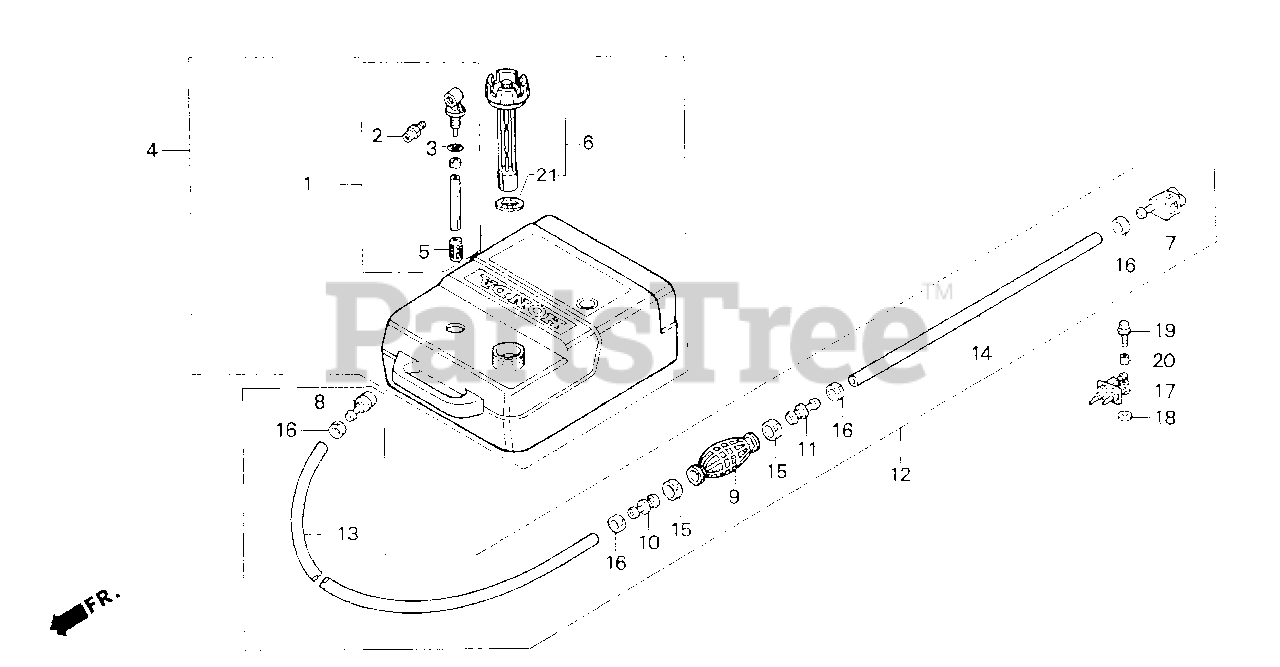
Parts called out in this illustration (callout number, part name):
1	JOINT ASSY., FUEL
2	FITTING, QUICK DISCONNECT
3	O-RING
4	TANK ASSY., FUEL
4	TANK, FUEL (25 LITER)
5	FILTER, FUEL
6	CAP, FUEL FILLER
7	CONNECTOR SET, FUEL
7	CONNECTOR ASSY. A, FUEL
8	CONNECTOR, FUEL
9	PRIMER BULB
10	VALVE, IN.
11	VALVE, OUTLET
12	TUBE ASSY., FUEL
13	TUBE, FUEL LONG (7.5X2000)
14	TUBE, FUEL SHORT
15	BAND, TUBE CLIP (20MM)
16	BAND, TUBE CLIP (12.5MM)
17	CONNECTOR SET, FUEL
17	CONNECTOR ASSY. B, FUEL
18	WASHER, PIVOT
19	BOLT, FLANGE (6X20)
20	COLLAR, DISTANCE (6MM)
21	GASKET, FUEL CAP
